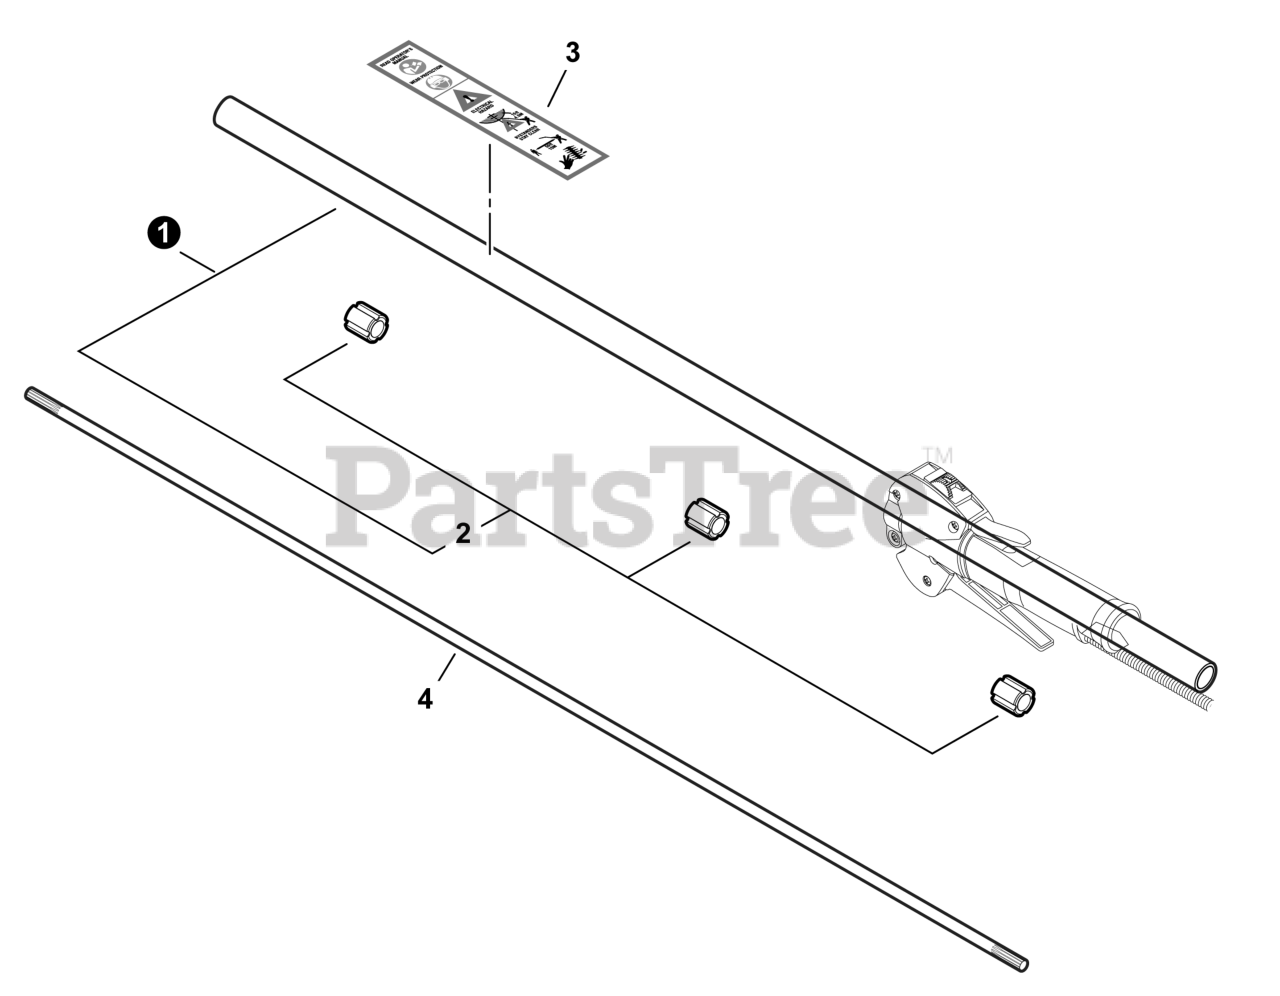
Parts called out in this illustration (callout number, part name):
1	MAIN PIPE ASSY
2	BUSHING
3	LABEL - CAUTION
4	MAINSHAFT Ø6×790 MM
